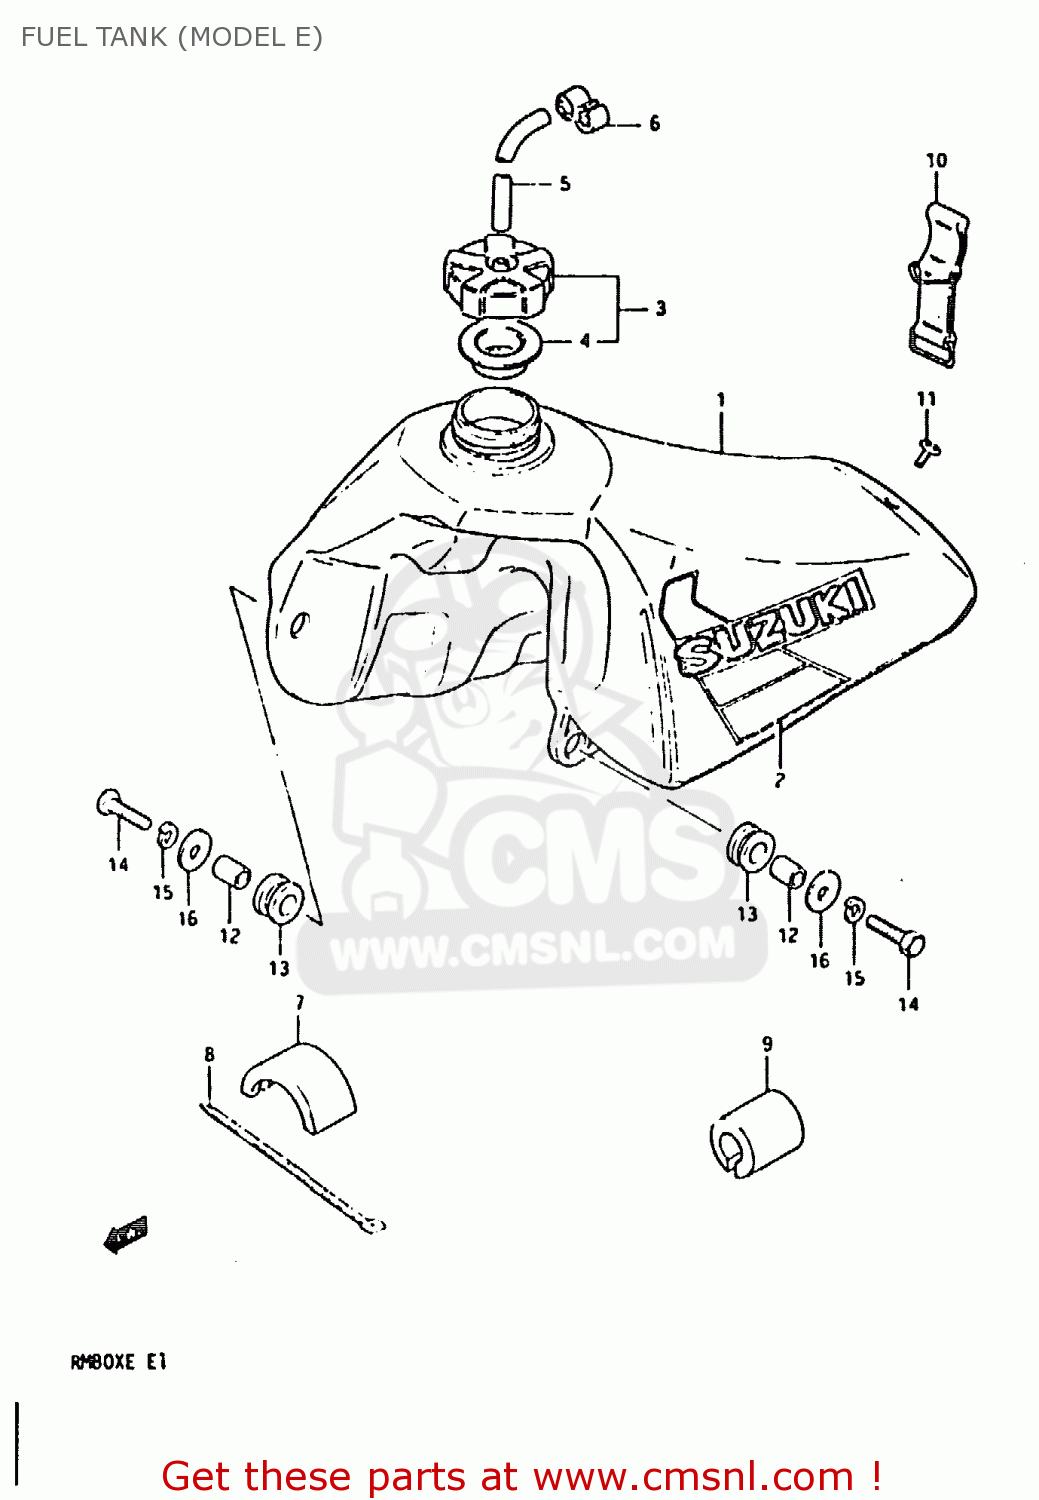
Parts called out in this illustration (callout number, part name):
1	TANK ASSEMBLY,FUEL
2	TAPE SET,FUEL TANK
3	CAP SET,FUEL TANK
4	GASKET,FUEL TANK CAP (NAS)
5	HOSE
6	CLAMP,FUEL TANK BREATHER HOSE
7	CUSHION,FUEL TANK UPR FR
8	CLAMP
9	CUSHION,FUEL TANK UPR RR
10	BAND
11	SCREW (6X15)
12	SPACER (6.8X10X11.5)
13	CUSHION
14	BOLT
15	LOCK WASHER
16	WASHER (6.5X24X1.6)
